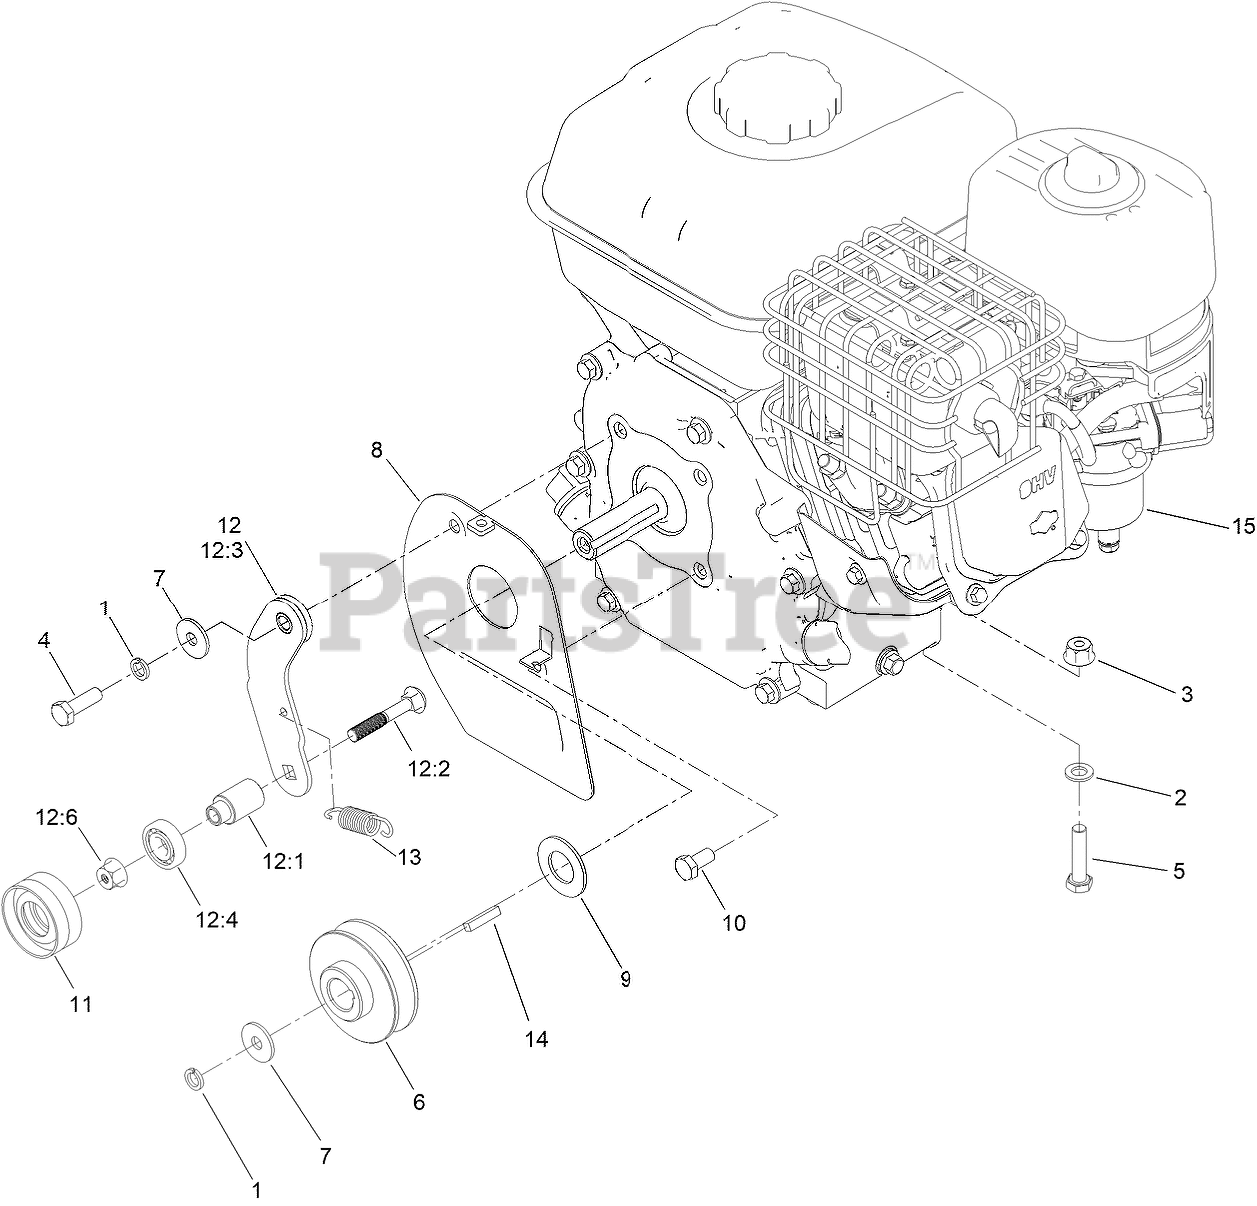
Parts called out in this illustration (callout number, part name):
1	WASHER- LOCK, SPRING
2	WASHER
3	NUT-FLANGE, HEX
4	SCREW-HH
5	BOLT
6	PULLEY
7	SPACER-SHAFT
8	PLATE-PULLEY, ENGINE
9	SPACER-SHAFT
10	BOLT-HEX
11	PULLEY
12	PULLEY ARM ASM
12:1	SLEEVE
12:2	BOLT-CARRIAGE
12:3	PULLEY ARM WELDED ASSY
12:4	BEARING
12:6	NUT-LOCK, PREVAILING TORQUE
13	SPRING
15	ENGINE
